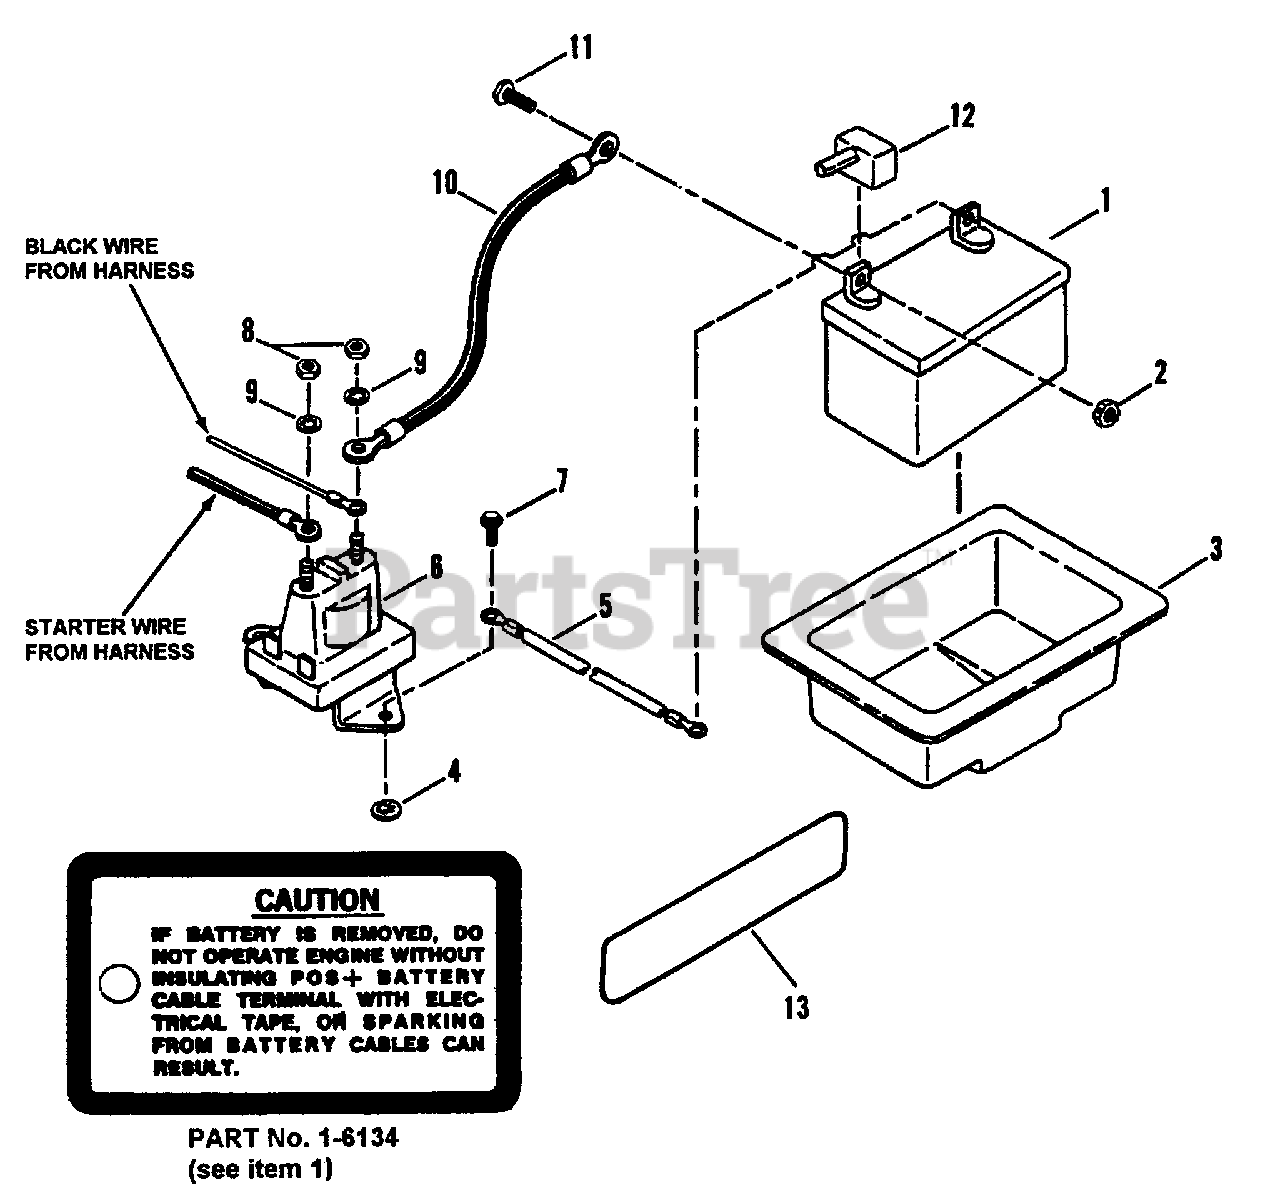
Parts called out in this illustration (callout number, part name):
1	KIT, Battery
2	NUT, 1/4-20 Hex Center Lock, Grade B or 5
3	TRAY, Battery
4	RETAINER, 1/4" Bolt
5	CABLE, Ground (Black)
6	SOLENOID
7	SCREW, 1/4-20 x 1/2" Self-Tapping
8	NUT, 1/4-20 Hex Jam
9	WASHER, 1/4 Internal Tooth Lock
10	CABLE, Positive (Red)
11	SCREW, 1/4-20 x 5/8" Hex Head Cap, Grade 5
12	COVER, Positive Terminal
13	DECAL, Caution, Battery Installation
16134	Caution Tag
